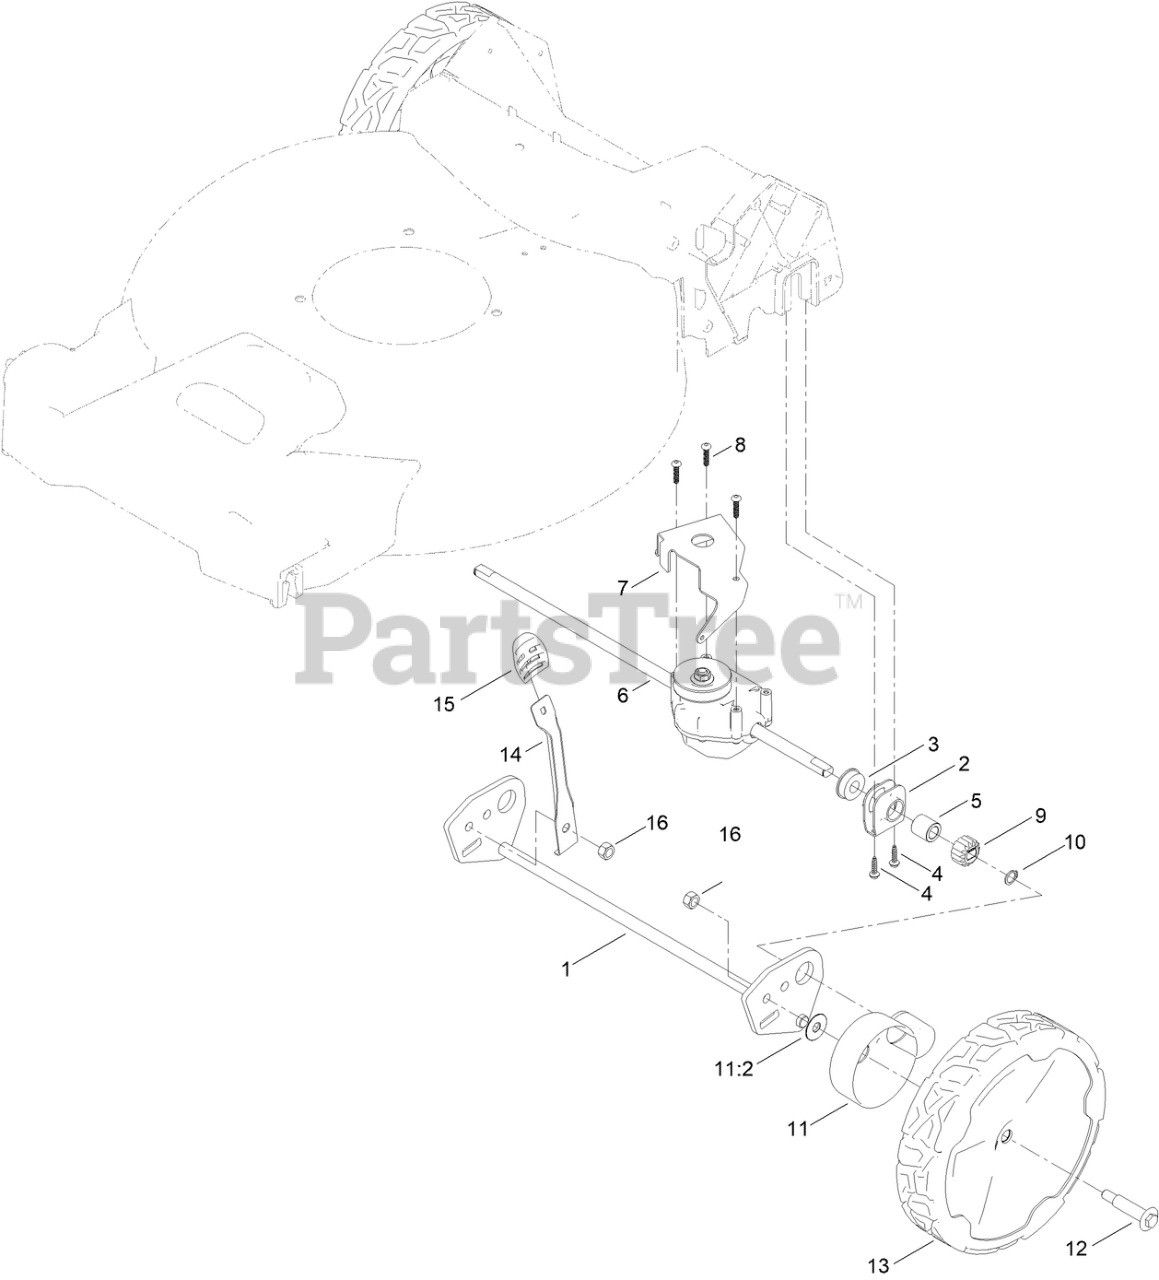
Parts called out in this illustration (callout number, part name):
1	AXLE-REAR, WA
2	RETAINER-BEARING
3	BEARING-BALL
4	SCREW-PLASTIC, HWH
5	BUSHING-SLEEVE
6	TRANSMISSION (7:1 RATIO)
7	BRACKET-TRANSMISSION
8	SCREW-PLASTITE
9	GEAR-PINION, 15T
10	RING-RETAINING
11	ASM-COVER, GEAR (DK GRAY)
11:2	WASHER-STEPPED
12	BOLT-SHOULDER
13	ASM-9.65" WHEEL, GEARED
14	ARM-SPRING
15	KNOB-LEVER, HOC
16	LOCKNUT
